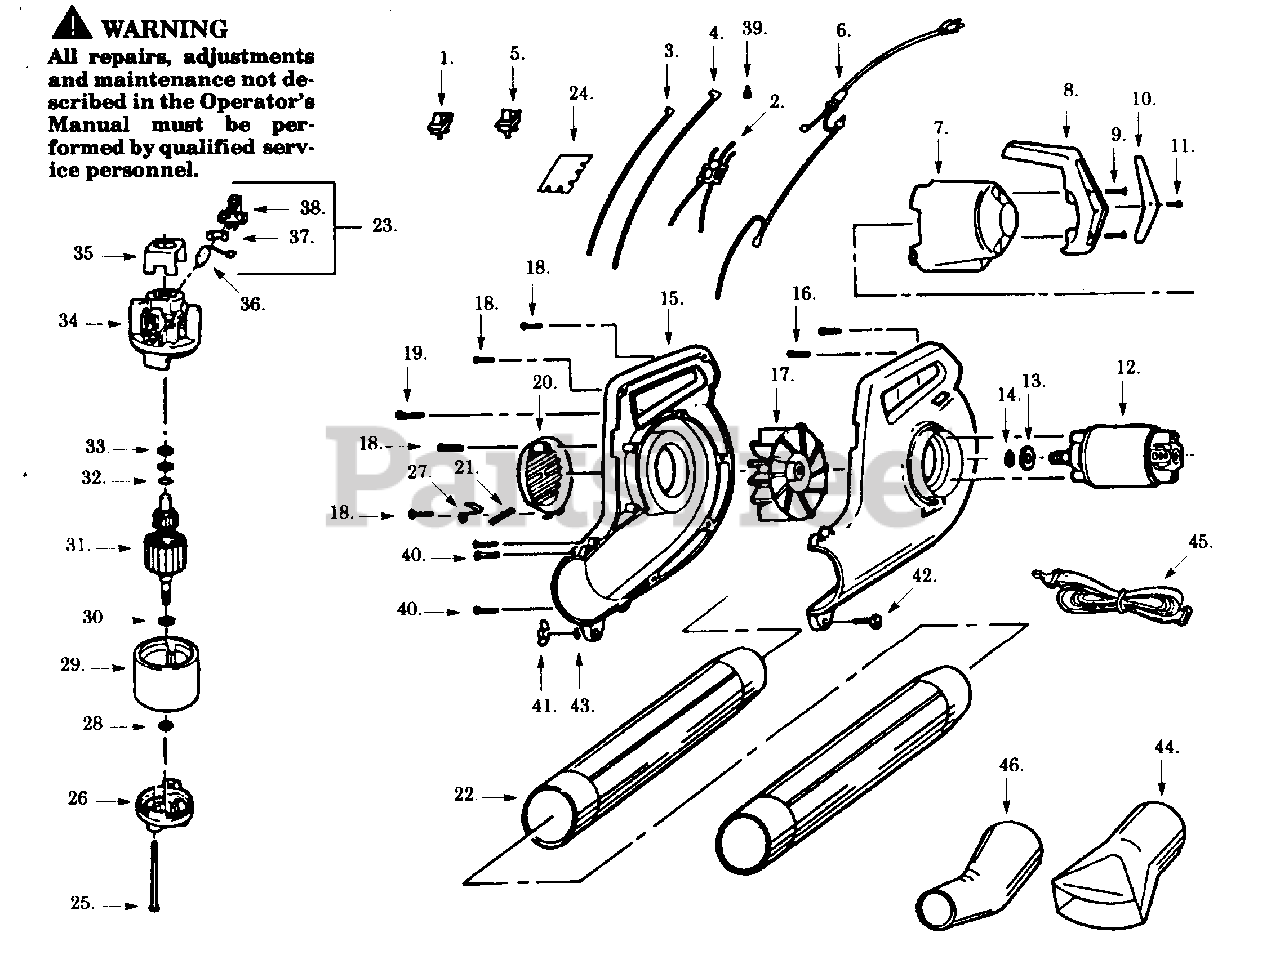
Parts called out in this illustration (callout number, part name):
1	On-Off Switch
2	P.C. Board Ass'y.
3	Lead Wire Ass'y.
4	Lead Wire Ass'y.
5	Speed Switch
6	Power Cord Ass'y.
7	Motor Cover
14	Retainer Ring
15	R.H./L.H. Housing
17	Impeller Ass'y.
20	Inlet Cover
21	Hinge Pin
22	Outlet Tube
23	Brush Kit (Incl. 36,37,38)
24	Mounting Board
26	Endbell Output
29	Field Ass'y.
30	Retainer Ring
31	Armature
32	Retainer Ring
34	Endbell (Brush)
35	Insulator
37	Brush Spring
38	Brush Holder
39	Connector
41	Wing Nut
44	Diffuser Ass'y.
45	Shoulder Strap
46	Curved Nozzle
